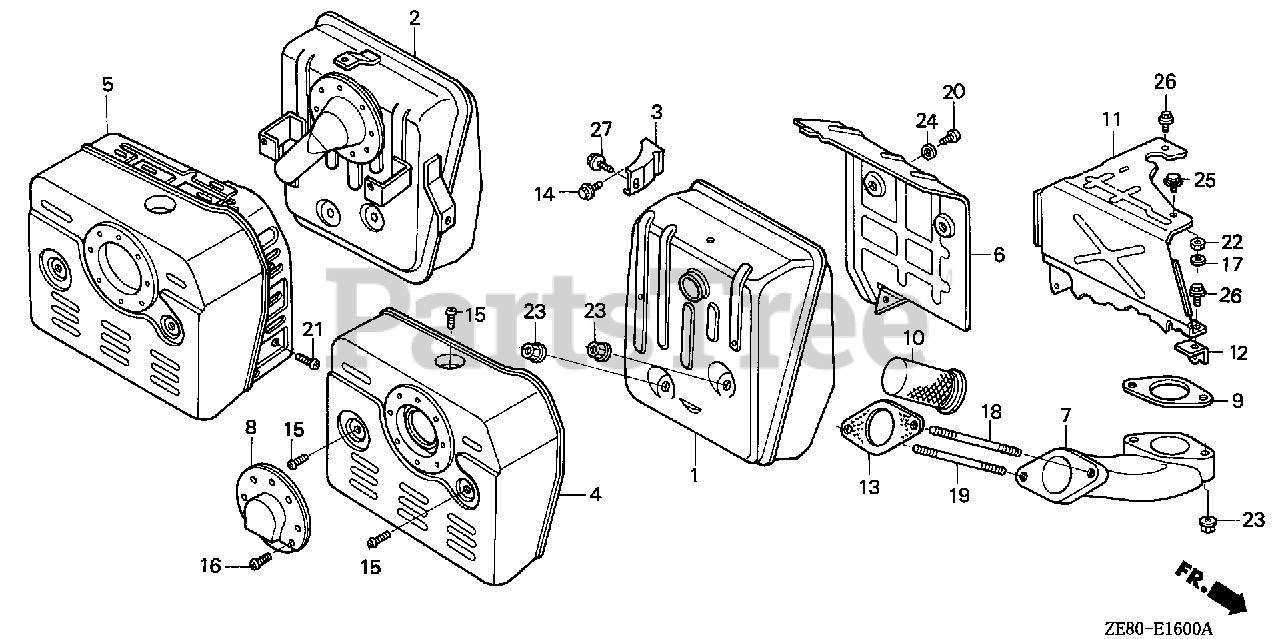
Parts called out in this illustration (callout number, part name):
1	MUFFLER
3	STAY, MUFFLER
4	PROTECTOR, MUFFLER (NOT AVAILABLE)
6	SEPARATOR, MUFFLER
7	PIPE, EX. (NOT AVAILABLE)
9	GASKET, EX. PIPE
11	COVER (LOWER) (NOT AVAILABLE)
12	STAY, COVER (LOWER)
13	GASKET, EX. PIPE
14	BOLT, FLANGE (8X16)
15	SCREW, TAPPING (5X8)
17	RUBBER (LOWER)
18	BOLT, STUD (8X60)
19	BOLT, STUD (8X70)
20	SCREW, PAN (6X6)
22	NUT, HEX. (6MM) (NOT AVAILABLE)
23	NUT, FLANGE (8MM)
24	WASHER, PLAIN (6MM)
25	BOLT, FLANGE (6X10)
26	BOLT, FLANGE (6X12)
27	BOLT, FLANGE (8X14)
